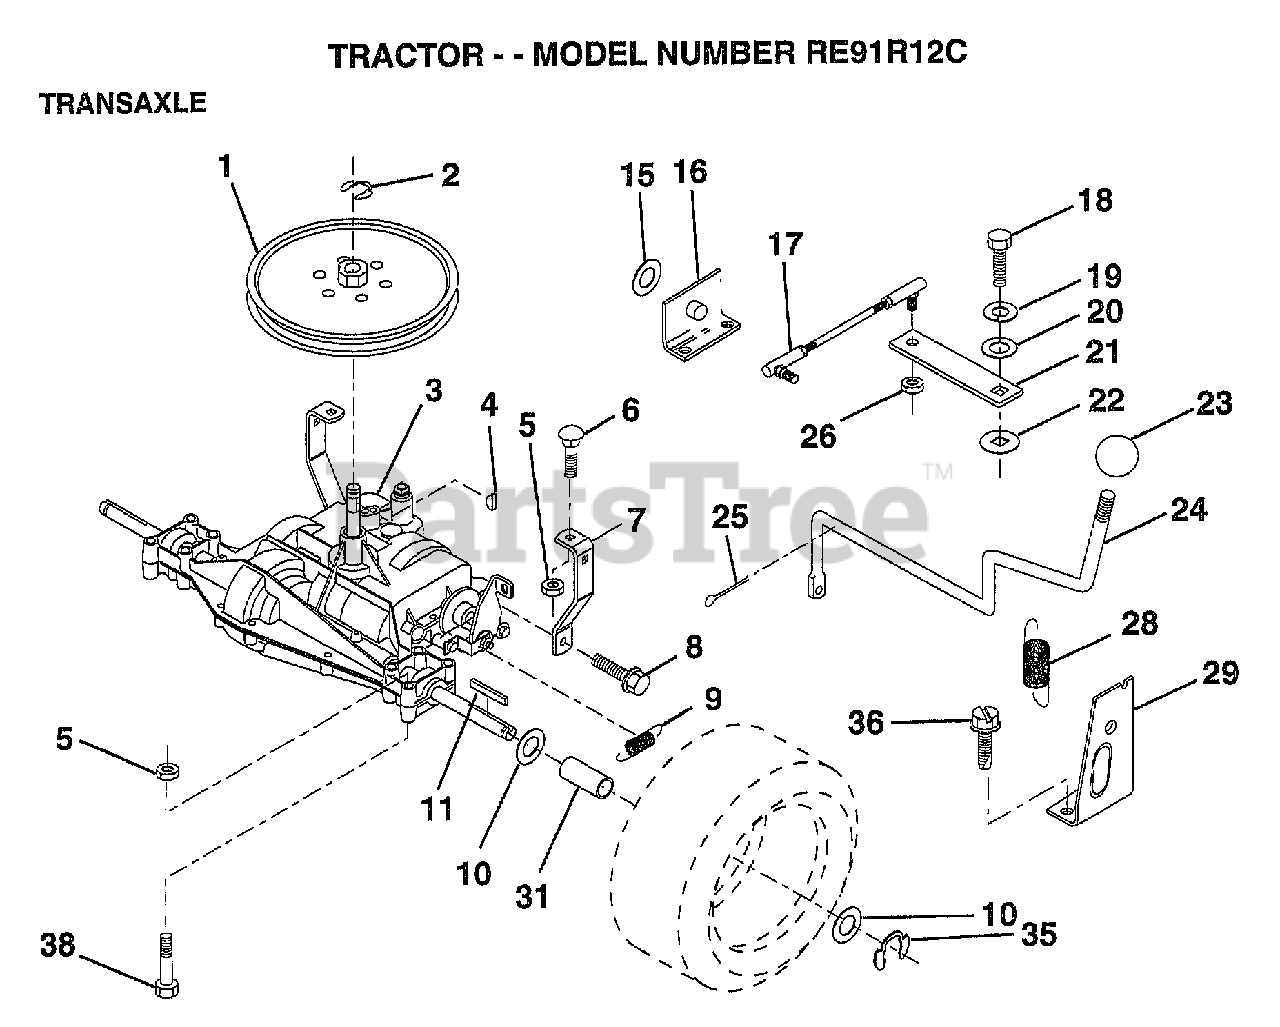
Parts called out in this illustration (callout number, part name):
1	PULLEY
6	BOLT
7	"STRAP,TORQUE"
8	SCREW
9	SPRING.BRAKE.RETU
10	WASHER
11	SQUARE KEY
16	"SUPT,HDLE SHT LH"
17	LINK SHIFT
18	BOLT.1/4-28.W/PAT
19	LOCKWASHER
20	WASHER LT
22	WASH-SHFT PLT LT
23	KNOB T (1/2-HOLE)
24	"ROD,SHIFT"
25	PIN COTTER 1/8
26	NUT.LOCK.5/16-24
28	"SPRING,EXT"
29	"SUPT,HDLE RH"
31	SPACER AXLE
35	E-RING LT
36	SCREW
38	BOLT.HX.FLG.5/16
